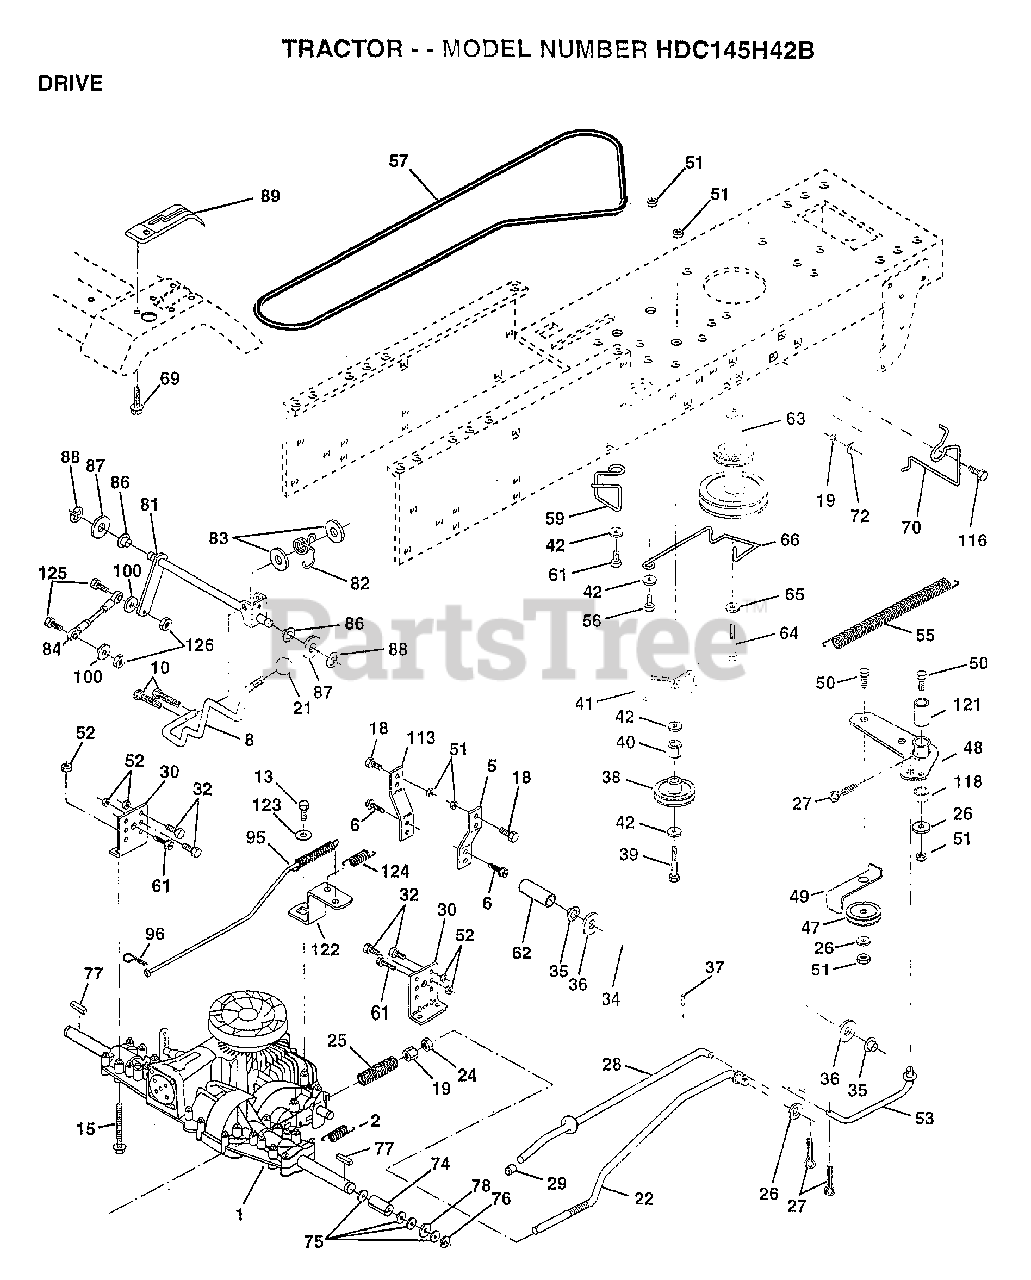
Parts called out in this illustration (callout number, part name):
1	TRANSAXLE, PEERLESS
2	SPRING.BRAKE.RETU
5	STRAP TORQUE
6	SCREW
8	ROD SHIFT FEND LT
10	PIN COTTER 1/8
13	BOLT.1/4-28.W/PAT
15	BOLT.HX.FLG.5/16
18	BOLT
19	NUT
21	KNOB T (1/2-HOLE)
22	BRAKE ROD
24	NUT
25	SPRING ROD LT
26	WASHER
27	COTTER PIN
28	ROD.BRAKE.PARK.LT
29	PLUNGER CAP T
30	TRANSAXLE MTG BKT
32	BOLT
34	SHAFT ASM-PEDAL F
35	NYLON BEARING
36	WASHER LT
38	PULLEY.IDLER.FLAT
39	BOLT
40	SPACER T
42	WASHER
48	BELLCRANK ASM
49	RETAIN BELT
53	"LINK, CLUTCH T"
55	"SPRING, RETURN LT"
57	"V-BELT,GRD DRIVE"
59	KEEPER BELT CNTSP
61	SCREW
62	PEDAL COVER T
63	PULLEY.ENGINE
64	BOLT
65	LOCKWASHER
66	KEEPER-BELT
69	SCREW HEXWSH H-L
70	KEEPER BELT ENG
72	WASHER
74	"SPACER AXLE,PVST"
75	WASHER
76	E-RING LT
77	SQUARE KEY
78	WASHER
81	SHAFT ASM CROSS
82	"SPRING,TORSION"
83	WASHER
84	ROD TIE
86	BUSHING
87	WASHER D
88	KLIP RING
95	ROAD ASM BYPASS
96	RETAINER M
100	WASHER M
113	"STRAP,TORQUE"
116	BOLT RDHD 3/8-16
118	SPACER-BELLCRANK
121	NYLINER-CLUTCHING
122	"PLATE-BYPASS,PVST"
124	SPRING RETURN
